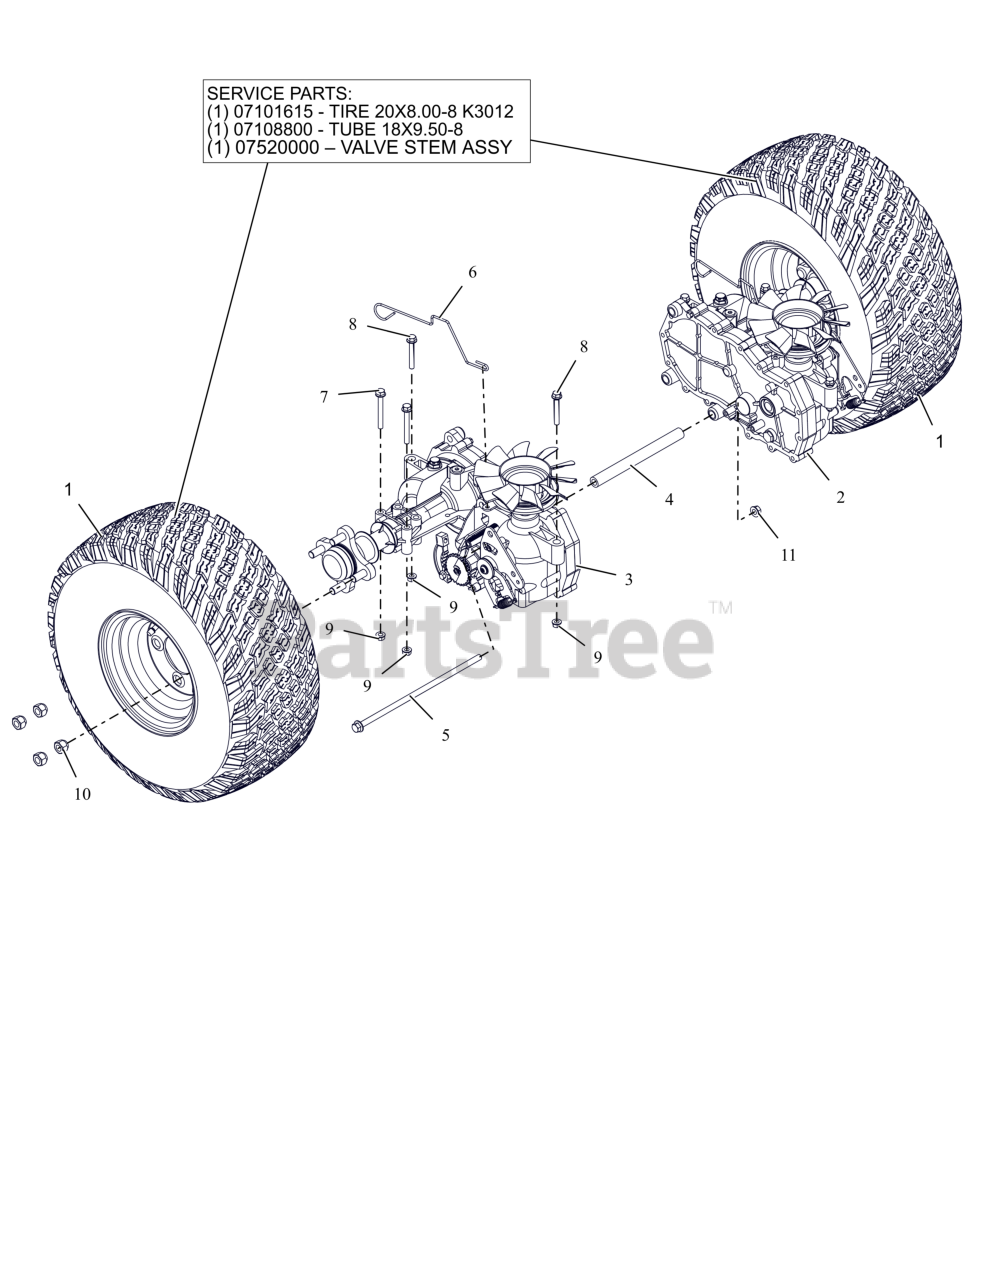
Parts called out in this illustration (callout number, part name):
1	ASM-WHL/TIRE 20X8.00-10 TURF
1	Tire, 20x8.00-8 K3012
1	TUBE 18X6.50/8.50/9.50-8/20X8.00/10.00-8
1	VALVE STEM ASS'Y
2	TRANSAXLE- SERVICEABLE EZT -LH
3	TRANSAXLE- SERVICEABLE EZT -RH
4	SPCR, TRANSAXLE .438 ID X .750 OD X 8.18 (BLACK)
5	BLT, HEX-FLG 0.375-16X11.5 GR5 ZC120
6	WIRE- DUMP VALVE LEVER
7	BLT,HEX-FLG .31-18X2.75 G5 ZCC
8	BLT,HEX-FLG .31-18X2.25 G5 ZCC
9	NUT,LK-CTR-FLG .31-18 GF ZCC
10	NUT, WHEEL .50-20 ZCC
11	NUT-LK-CTR-FLG .375-16 GF ZCC
